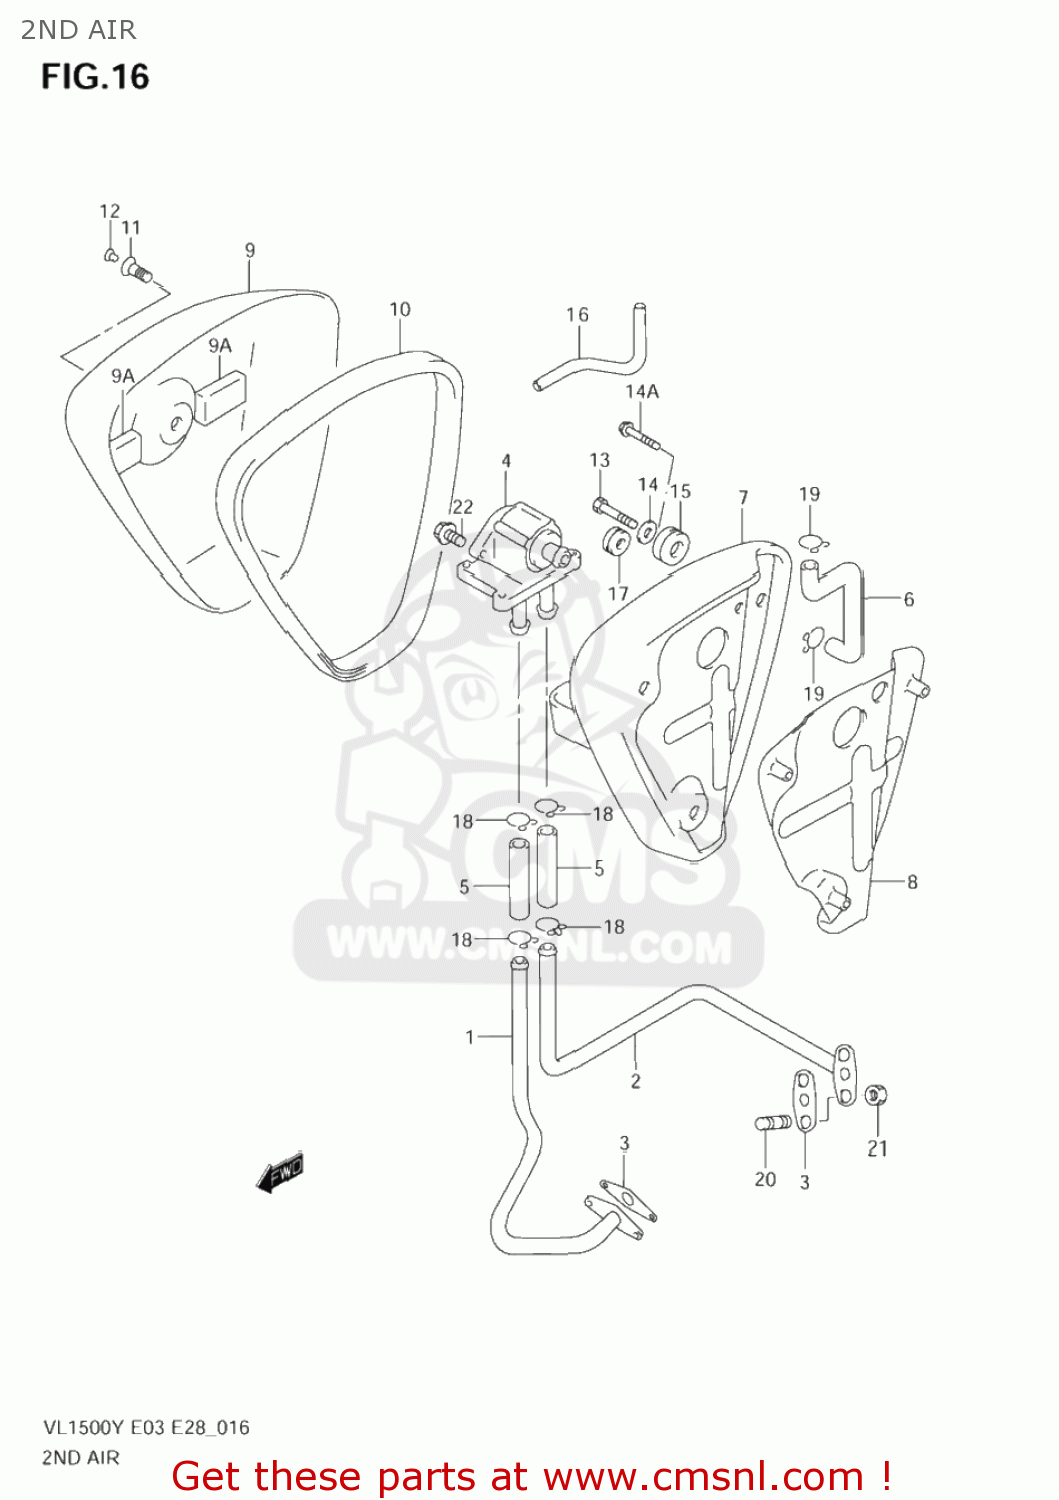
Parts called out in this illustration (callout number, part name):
1	PIPE,2ND AIR FR
2	PIPE,2ND AIR RR
3	GASKET,2ND AIR PIPE (NAS)
4	VALVE ASSY,2ND AIR
5	HOSE,2ND AIR VALVE
6	HOSE,2ND AIR CLEANER
7	BRACKET,2ND AIR SPRT
8	PLATE,2ND AIR HEAT GUARD
9	COVER ASSY,2ND AIR
9A	PAD,HEAD COVER CAP
10	CUSHION
11	BOLT(8X25)
12	CAP(OD:11)
13	BOLT
14	WASHER
14A	BOLT(6X37)
15	CUSHION
16	HOSE(3.5X7.5X600)
17	CUSHION
18	CLIP
19	CLIP
20	STUD BOLT
21	NUT
22	BOLT
